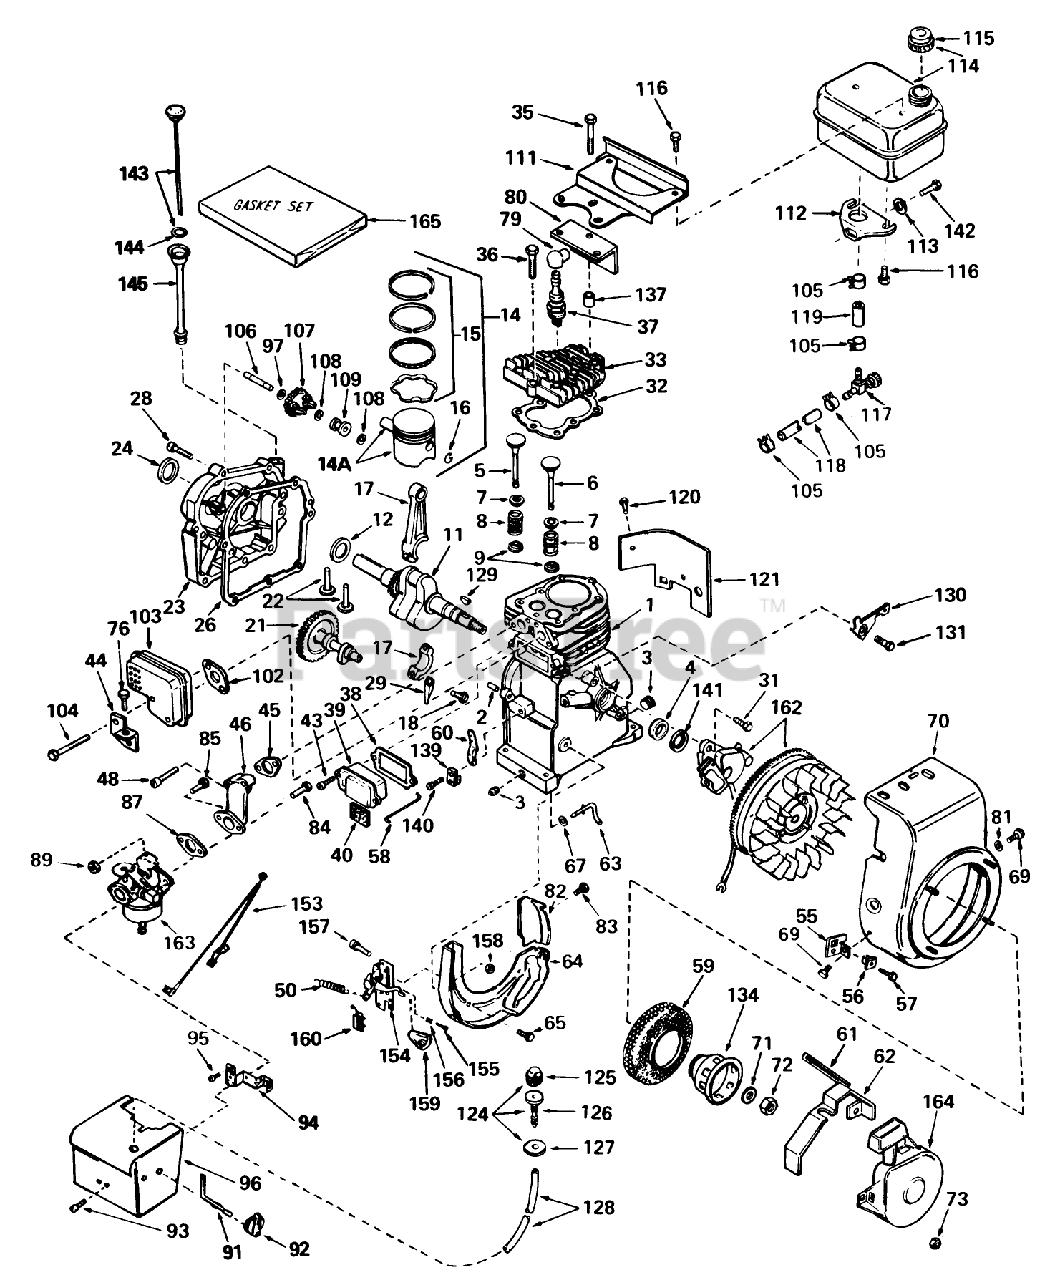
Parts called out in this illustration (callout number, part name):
1	Cylinder Assy. (Incl. #2, 3 4)
2	Pin-Dowel
3	Plug-Drain, Oil (SQH 1/4-18)
4	Seal-Oil
5	Valve, Intake (Standard) (Incl. Nos. 7, 9 10)
5	Valve, Intake (1/32" Oversize) (Incl. Nos. 7, 9 10)
6	Valve, Exhaust (Standard) (Incl. Nos. 8, 9 10)
6	Valve, Exhaust (1/32" Oversize) (Incl. Nos. 8, 9 10)
7	Cap-Upper Valve Spring
8	Spring-Valve
9	Cap-Valve, Spring
11	Crankshaft Assembly
12	Washer-Thrust
14	Piston, Pin Ring Assy. (Std.)(Incl. Ref. #13A, 14 15)
14	Piston,Pin Ring Assy. (.010 over-size)(Incl. Ref. #13A, 14 15)
14	Piston, Pin Ring Assy. (Incl. Nos. 13A, 14 15)(.020 oversize)
14A	Piston Pin Assy. (Incl . Ref. . #14) (Std.)
14A	Piston Pin Assy. (Incl. Ref. #14) (.010 Oversize)
14A	Piston Pin Assy. (.020 oversize) (Incl. Ref. #14)
15	Ring Set Piston (Std.)
15	Ring Set Piston (.010 Oversize)
15	Ring Set Piston (.020 Oversize)
16	Ring-Retaining, Piston Pin
17	Rod Assembly, Connecting (Incl. Nos. 17 18)
18	Screw, Connecting Rod
21	Camshaft
22	Lifter-Valve
23	Cover, Cylinder (Incl. Ref. #24 106)
24	Seal-Oil
26	Gasket-Cylinder Cover
28	Screw (1/4-20 x 1-1/4)
29	Dipper, Oil
31	Screw
32	63573 GIL 42 SNWTHW
33	Head Cylinder
35	Screw (5/16-18 X 2)
36	Screw (5/16-18x1-1/2)
37	Plug, Spark (J17LM or equiv.)
37	Plug, Spark (Champion RCJ-8)
38	Gasket Breather
39	Breather Assembly (Incl. Nos. 52 84)
40	Element-Breather
43	Screw
44	Bracket-Cover, Carburetor
45	Gasket, Intake
46	Pipe, Intake
48	Screw (1/4-20 x 1-19/32)
50	Spring-Extension
55	Bracket
56	Grommet
57	Screw
58	Link-Governor to Throttle
59	Screen-Starter
60	Lever-Governor
61	Seal, Snowguard
62	Guard-Starter
63	Rod-Governor
64	Baffle-Blower Housing
65	Screw (1/4-20x19/32)
67	Washer-Flat
69	Screw
70	Housing, Blower
71	Washer-Spring
72	Hex Nut
73	Nut and Lock Washer (1/4-28)
76	Screw (10-24 x 3/8)
79	Cover-Spark Plug
80	Baffle-Heat
81	Washer
82	Baffle-Extension
83	Screw-Hex Washer Hd.
85	Screw-Fil. Hd.
87	Gasket
89	Nut and Lock Washer (1/4-28)
91	Rod-Choke
92	Knob-Control
93	Screw (8-32 X 5/16)
94	Bracket-Choke
95	Screw (10-32 x 1/2)
96	Cover, Carburetor
97	Washer-Flat
102	Gasket-Intake
103	Muffler
104	Screw-Fil. Hd.
105	Clamp-Line, Fuel
106	Shaft-Governor
107	Governor Gear ASM
108	Ring-Retaining
109	Spool-Governor
111	Plate-Fuel Tank
112	Bracket, Fuel Tank Lower
113	Washer
114	53023/VAR.10/16HP O
115	Cap, Fuel
116	Screw (1/4-15x7/8)
117	Valve-Shut Off
118	Line-Fuel
119	Line-Fuel (8.62)
120	Screw
121	Extension-Blower
124	Primer Assy. (Incl. Nos. 89, 90 91)
125	Bulb, Primer
126	Body, Primer
127	Retainer, Primer Bulb
128	Line, Primer
129	Key, FIywheel
130	Bracket-Hold Down
131	Screw (10-24 x 9/16)
134	Cup, Starter
137	pacer
139	Clamp-Lever, Governor
140	Screw
141	Gasket Stator
142	Screw Assembly
143	Dipstick
144	O-Ring
145	Tube Fill
153	Wire-Ground
154	Control Assembly, Speed (Incl. Ref. #155 thru 158 160)
155	Screw
156	Spring-Compression
157	Screw
158	Nut-Lock
159	Knob-Control
160	Terminal
162	Magneto
163	Carburetor (Incl. Ref. #87)
164	Starter Assy., Rewind
165	Gasket
